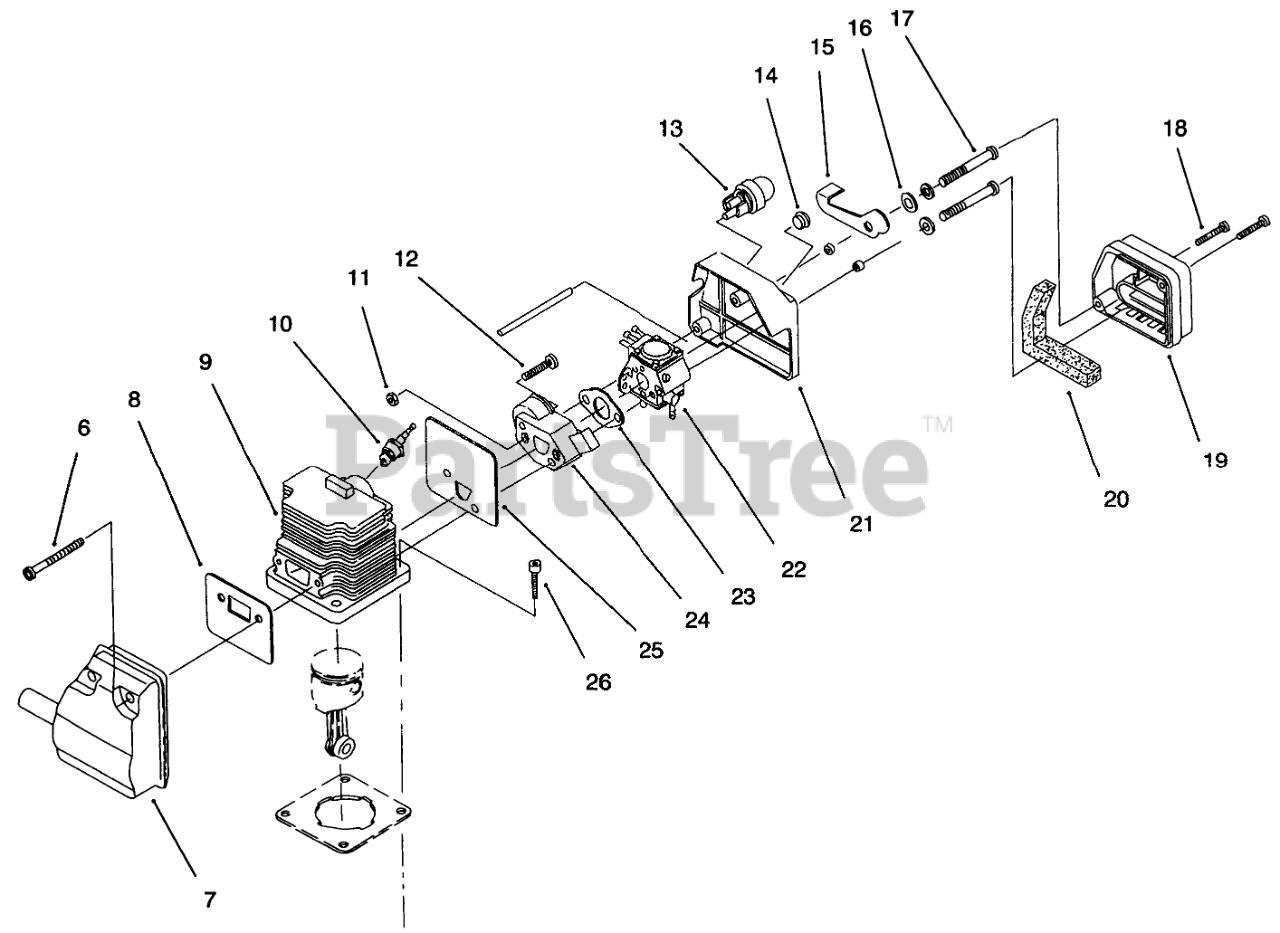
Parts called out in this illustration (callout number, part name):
6	MUFFLER MOUNTING SCREWS
7	MUFFLER ASSEMBLY
8	MUFFLER GASKET
9	CYLINDER
10	SPARK PLUG
11	SPACER NUT SET
12	SPACER SCREW SET
13	PRIMER & HOSE ASM
14	SWITCH PLUG
15	CHOKE LEVER
16	WAVEY WASHER
17	CARB MOUNTING ASM
18	Screw
19	AIR CLEANER COVER
20	FOAM AIR FILTER ELEMENT
21	Air Cleaner Base Asm.
22	ASM - CARBURETOR
23	CARB.GASKET(PK.10=1)
24	CARBURETOR SPACER ASM
25	CYL/CARB SPACER GASKET
26	SCREW
